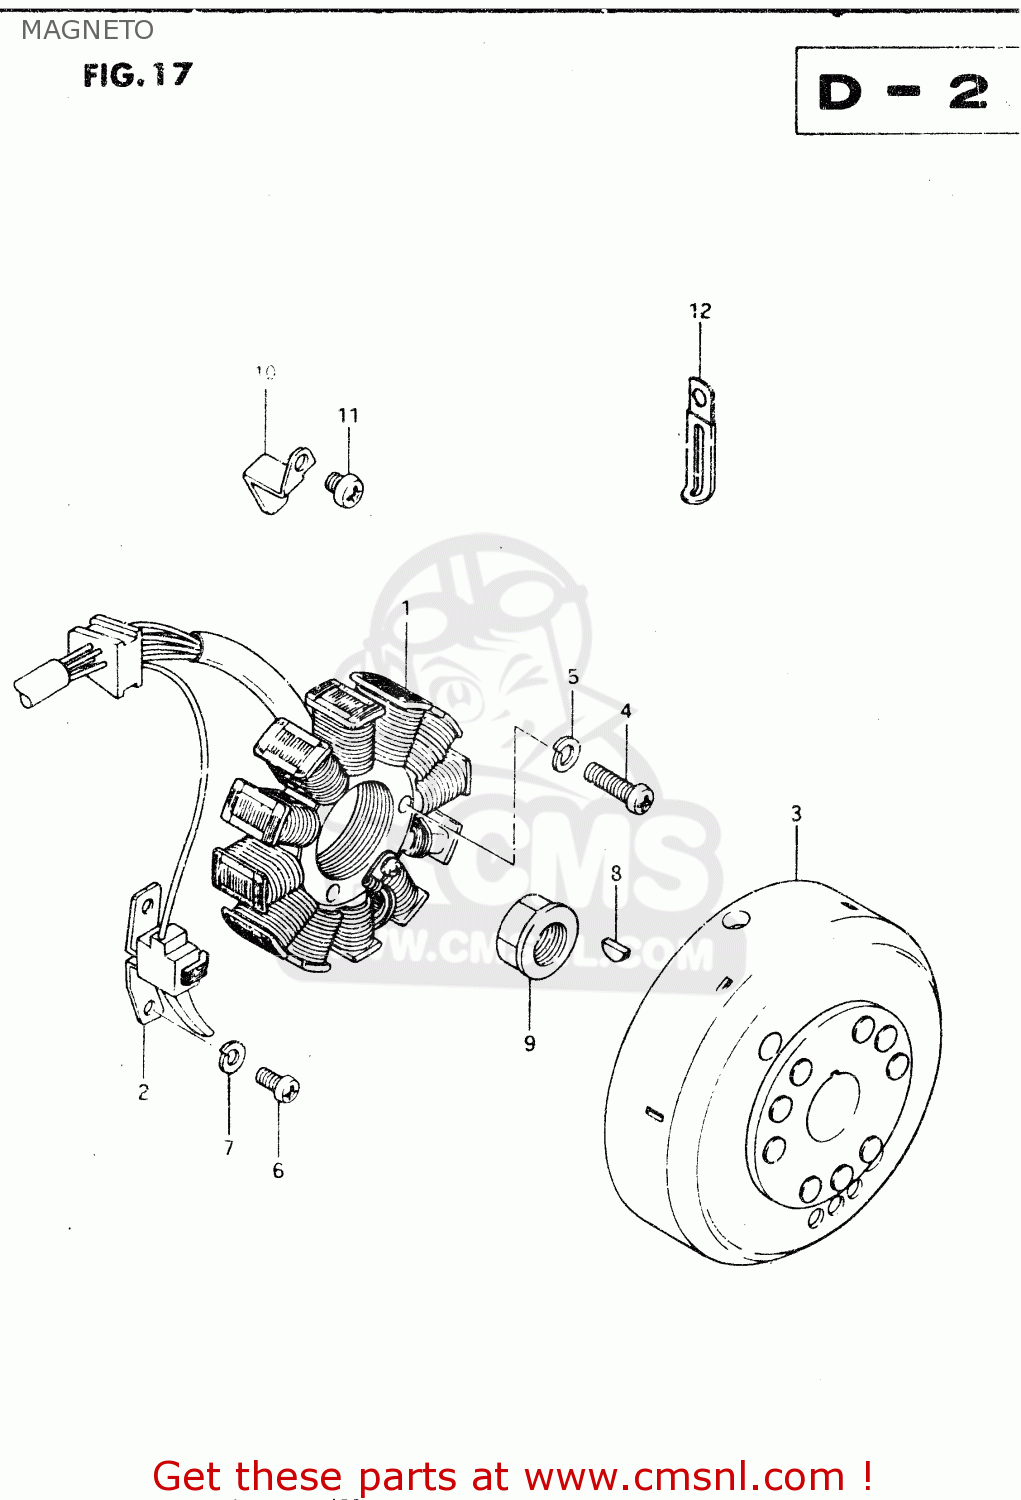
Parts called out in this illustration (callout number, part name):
1	STARTER ASSY
2	COIL,PICK UP
3	ROTOR,FLYWHEEL
4	SCREW
5	LOCK WASHER
6	SCREW
7	LOCK WASHER
8	KEY 4MM
9	NUT,GENERATOR ROTOR
10	CLAMP,MAGNETO LEAD WIRE
11	SCREW
12	CLAMP L:35
